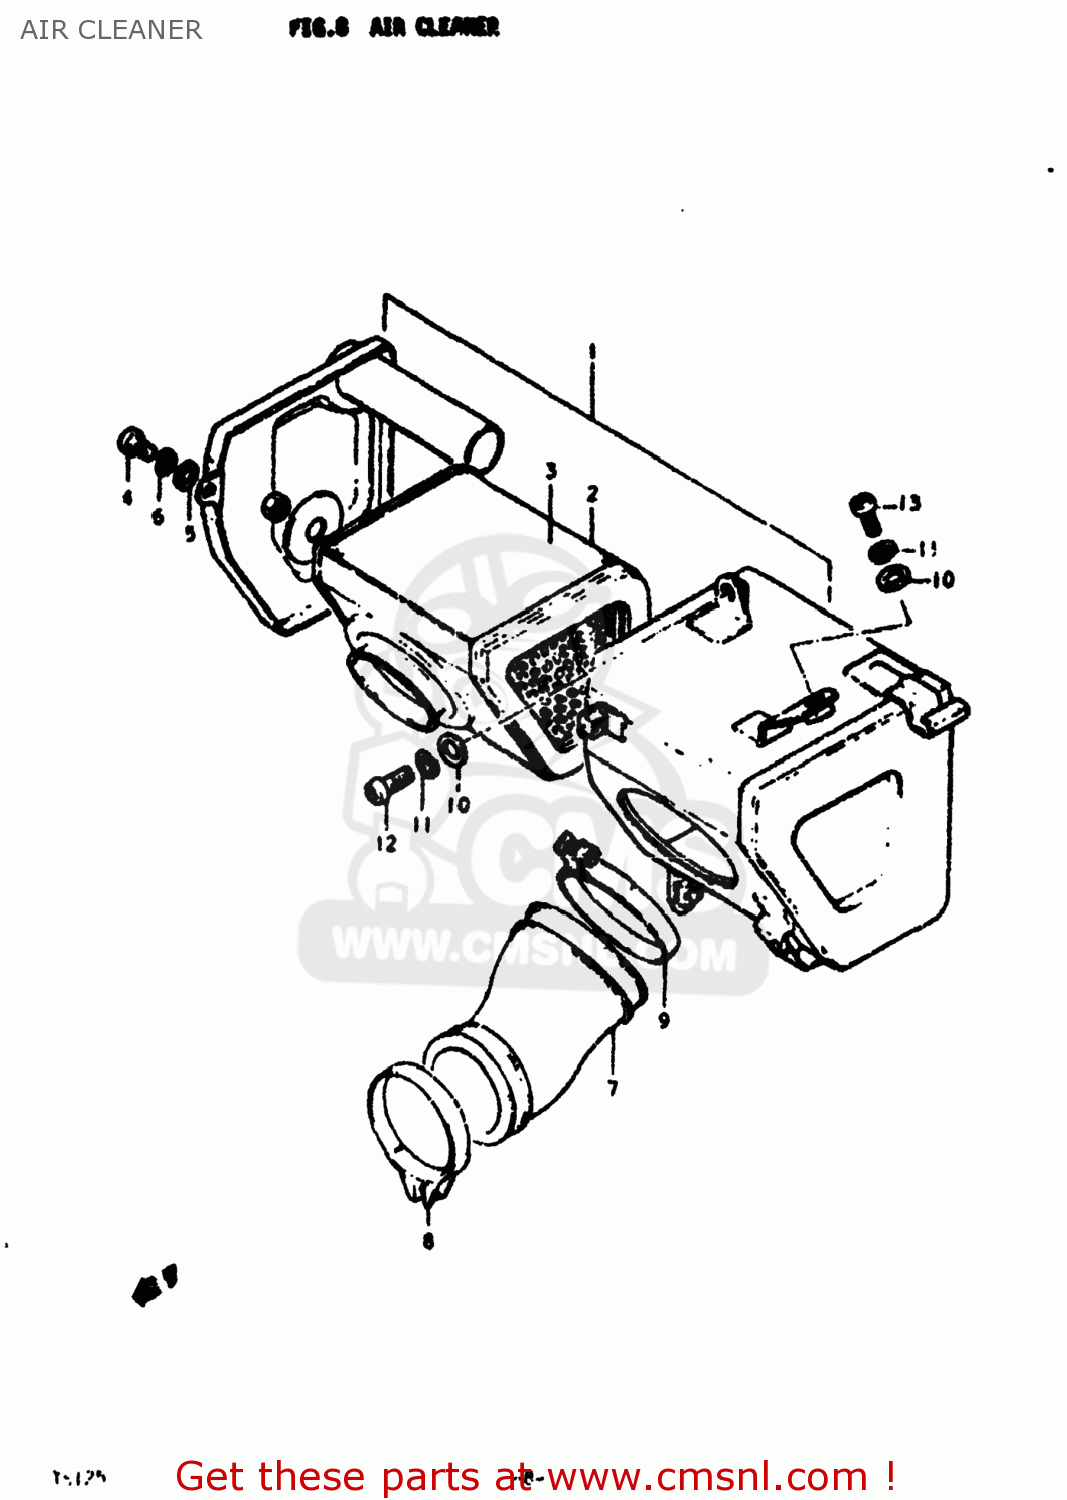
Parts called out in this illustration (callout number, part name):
1	CLEANER ASSEMBLY,AIR
2	FILTER,AIR CLEANER
3	FILTER
4	SCREW
5	WASHER
6	LOCK WASHER
7	HOSE,CARBURETOR AIR INLET
8	CLAMP
9	CLAMP
10	WASHER
11	LOCK WASHER
12	SCREW 6X12
13	SCREW
